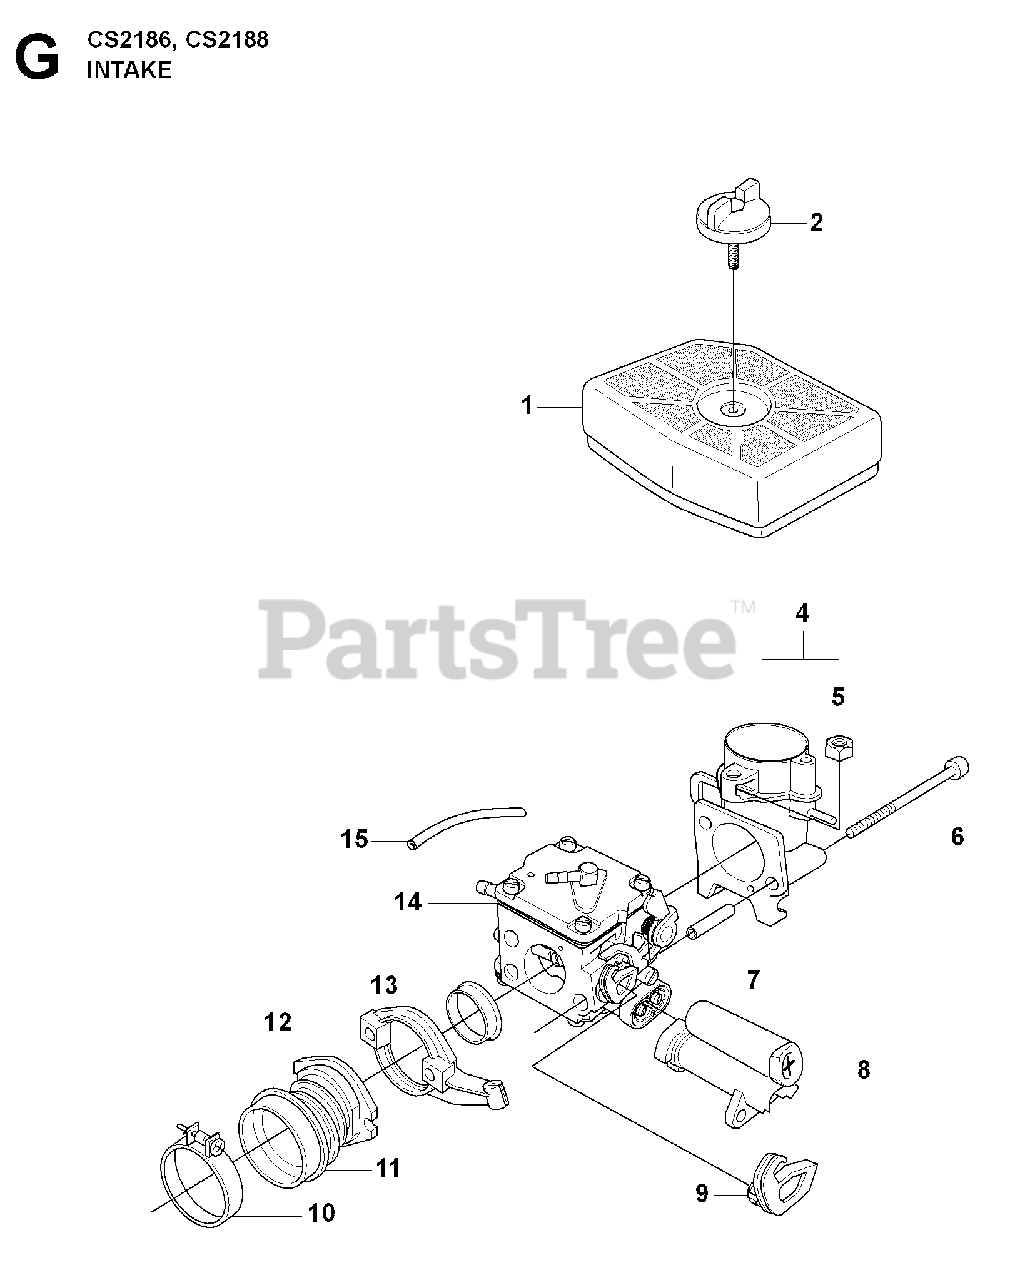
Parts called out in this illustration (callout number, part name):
1	AIR FILTER
4	FILTER HOLDER
5	NUT
8	GUIDE BUSHING
10	CLAMP
11	RP INTAKE PIPE
14	CARBURETOR
